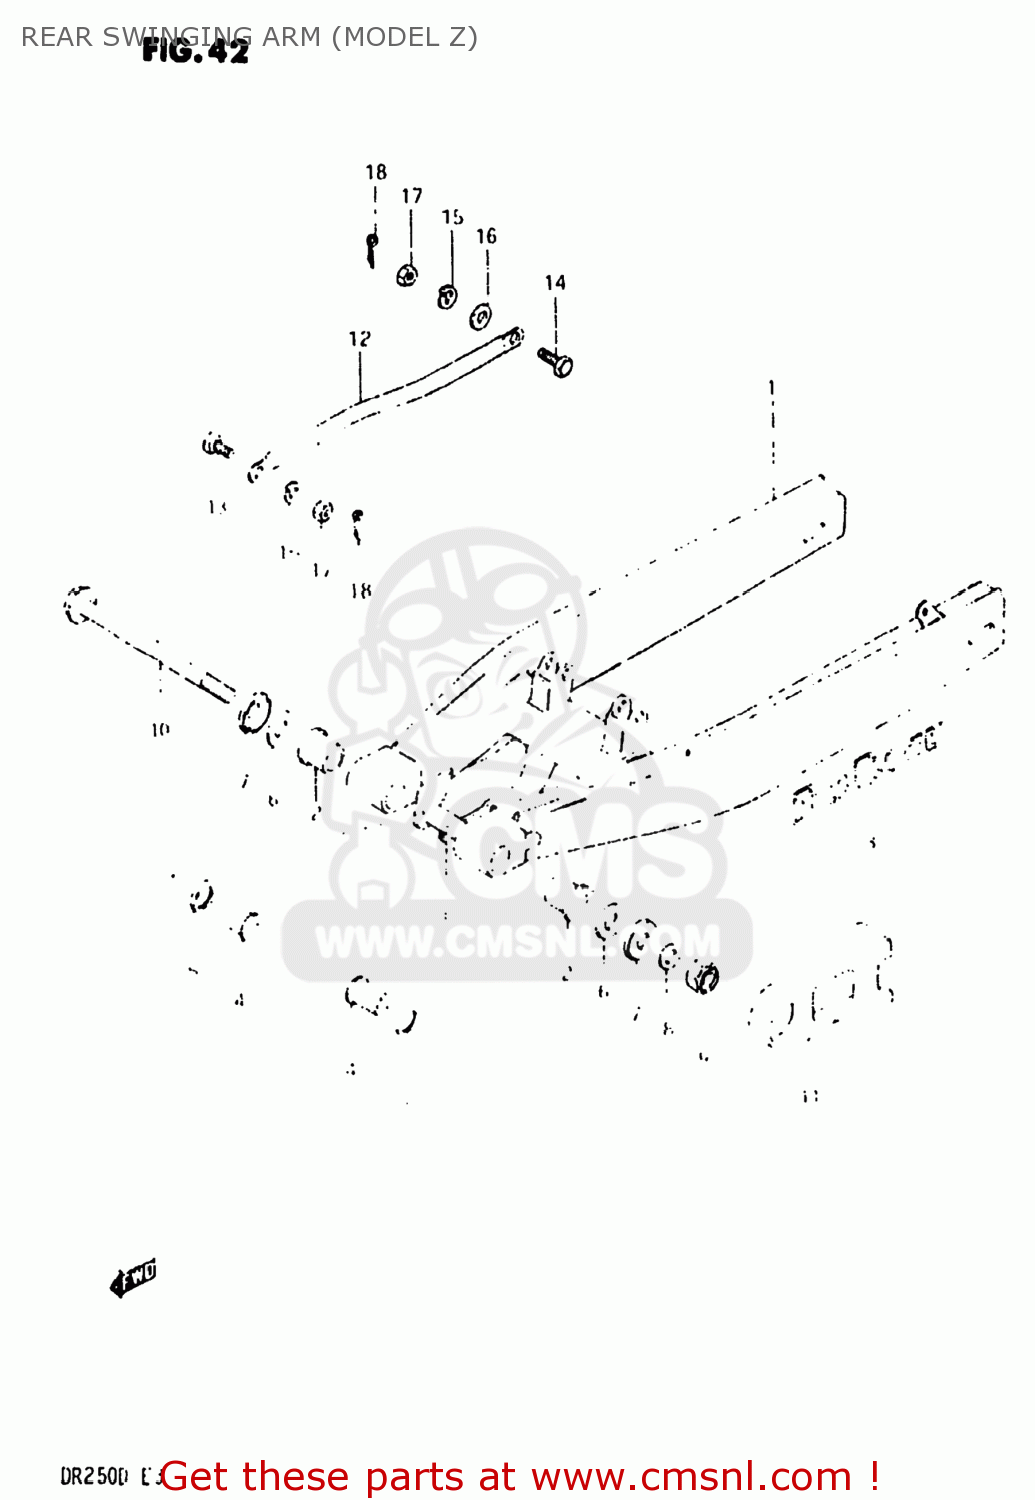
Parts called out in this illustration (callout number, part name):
1	SWING ARM ASSEMBLY,REAR
2	BUSHING,RR SWGARM PIVOT
3	EMBLEM,SWING ARM
4	SPACER,RR SWGARM PIVOT OUTER
5	SEAL,OIL(20X27X5)
6	WASHER
7	COVER,REAR SWING ARM DUST
8	WASHER
9	NUT 14MM
10	SHAFT,REAR SWING ARM
11	BUFFER,CHAIN TOUCH DEFLECTOR
12	LINK,REAR TORQUE
13	BOLT
14	BOLT(8X26.5)
15	LOCK WASHER
16	WASHER
17	NUT
18	PIN 20X20
